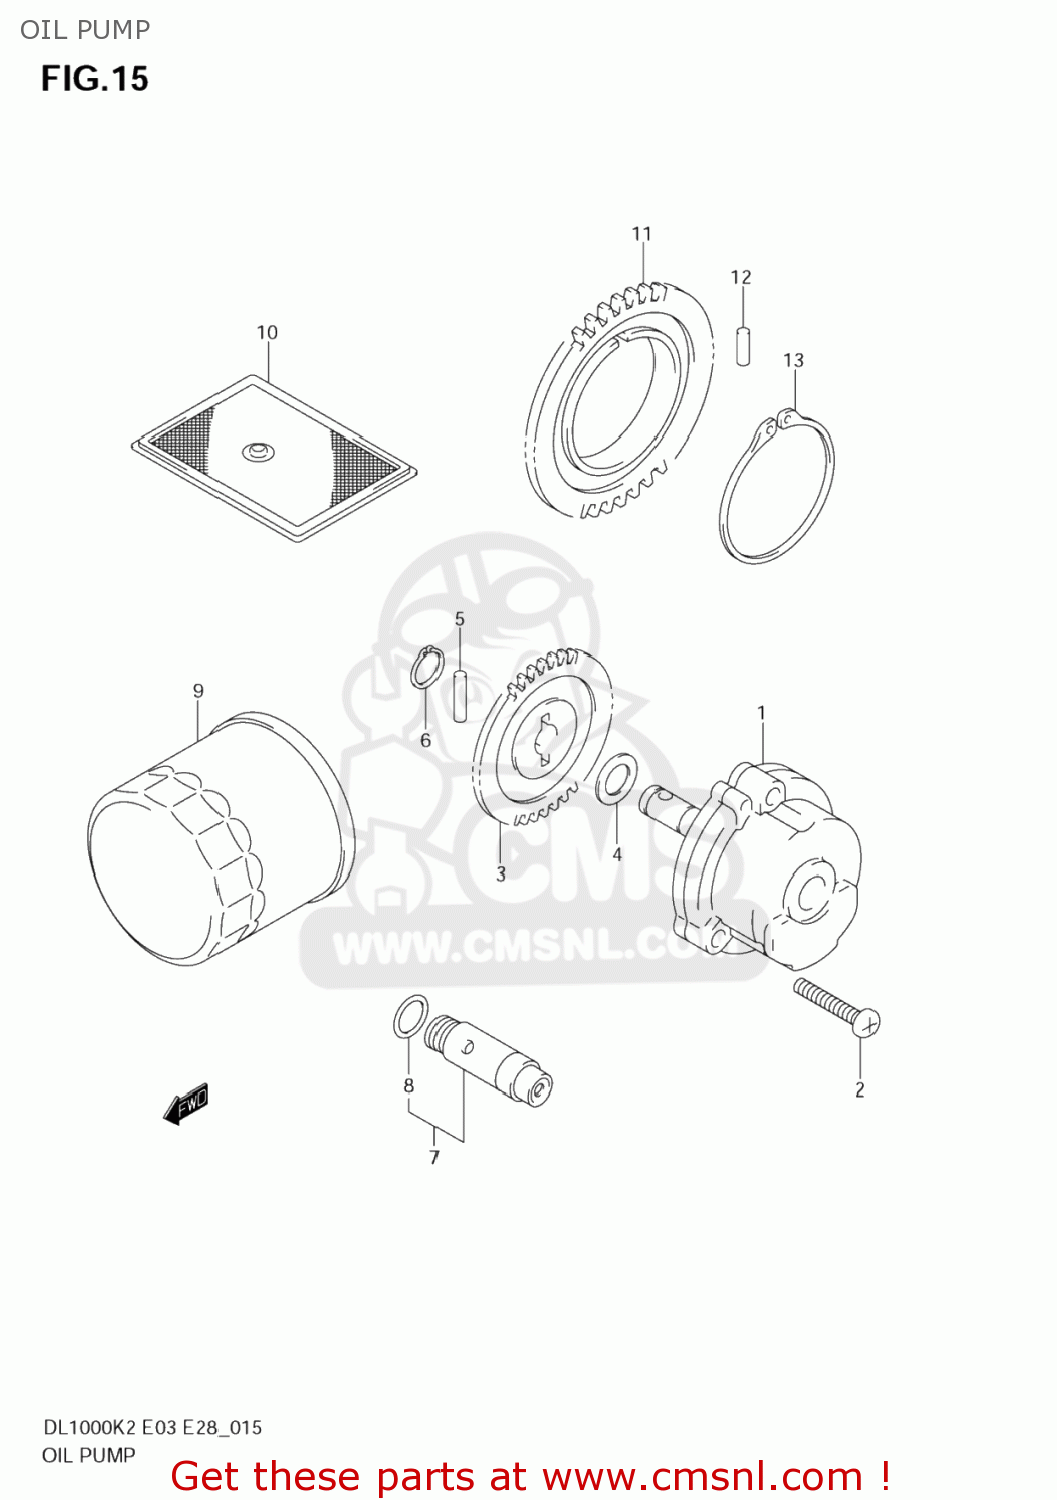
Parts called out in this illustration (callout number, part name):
1	PUMP ASSY,ENGINE OIL
2	SCREW
3	GEAR,OIL PUMP DRIVEN
4	SHIM(10X18X0.5)
5	PIN(4X15.8)
6	CIRCLIP,10MM
7	VALVE ASSY,OIL RELIEF(7K)
8	O RING(D:1.9,ID:13)
9	FILTER ASSY,EN
10	STRAINER,ENGINE OIL
11	GEAR,ENG OIL PUMP DRIVE
12	PIN(6X6)
13	CIRCLIP
